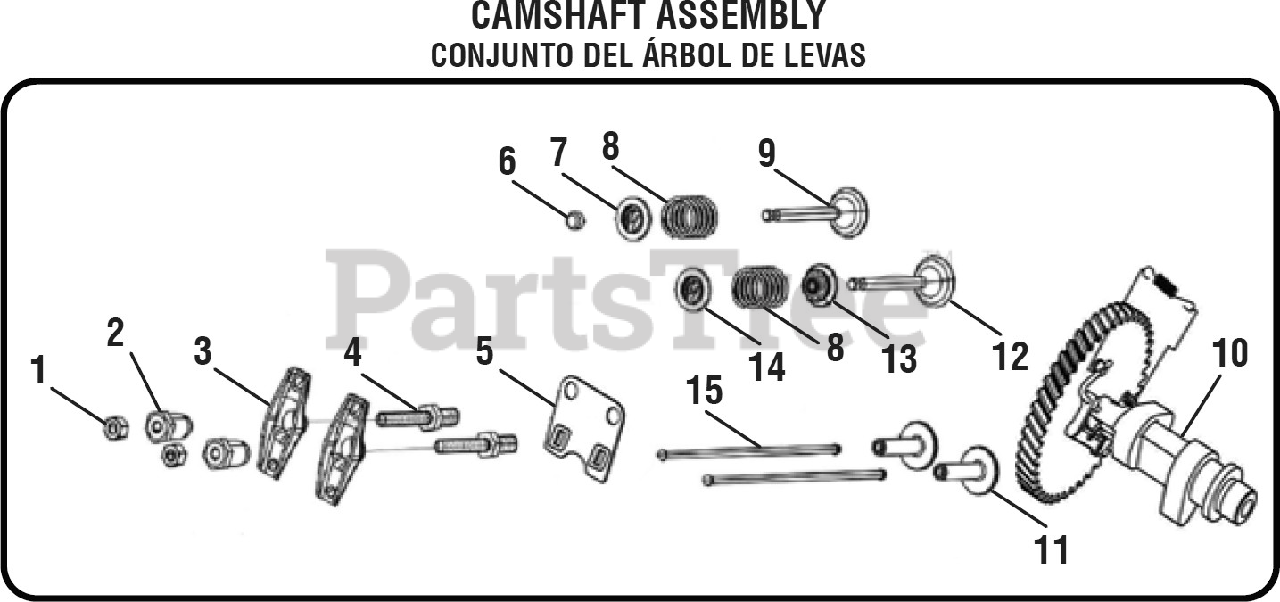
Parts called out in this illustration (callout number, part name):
1	Valve Lock Nut
2	Valve Adjusting Nut
3	Valve Rocker
4	Valve Adjusting Bolt
5	Lifter Stop Plate Assembly
6	Valve Rotator
7	Retainer, Exhaust Valve
8	Valve Spring
9	Exhaust Valve
10	Camshaft Assembly
11	Valve Tappet
12	Intake Valve
14	Valve Spring Seat
15	Valve Lifter
